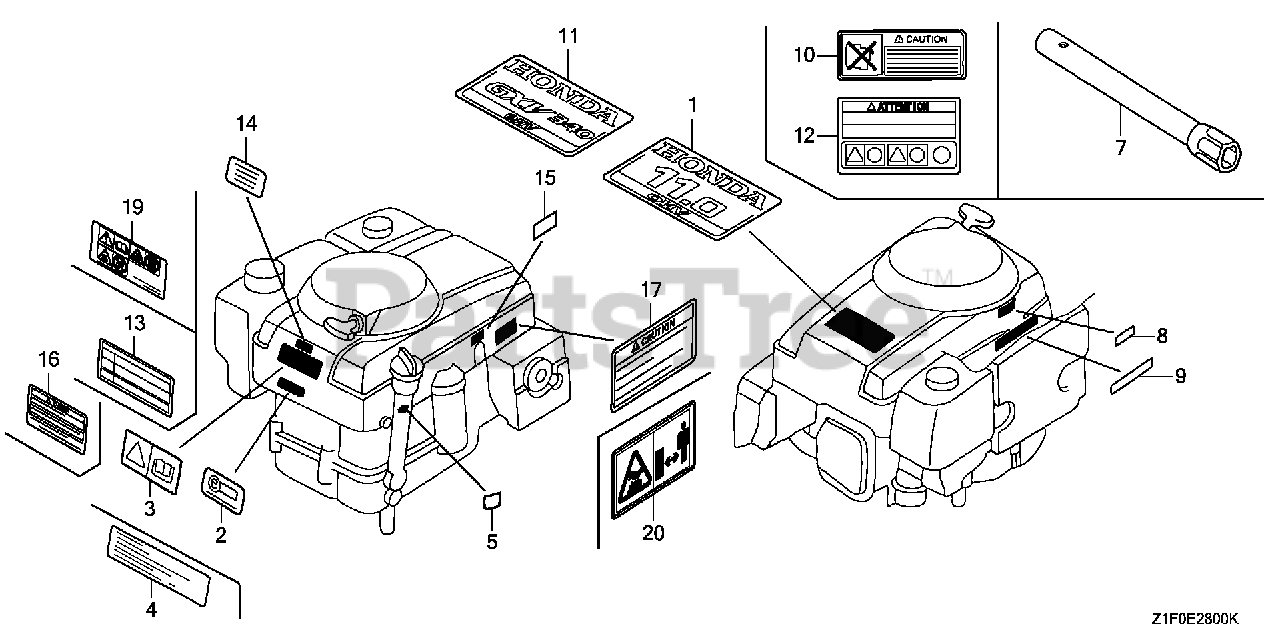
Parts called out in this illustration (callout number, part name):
1	EMBLEM, TOP COVER (11.0)
4	LABEL, CAUTION
5	MARK, TYPE (DP23)
7	WRENCH, BOX (P21)
8	LABEL, FUEL CAUTION
9	LABEL, HONDA NAME
10	LABEL, MAINTENANCE CAUTION
11	EMBLEM, TOP COVER (GXV340)
15	LABEL, WARNING (NOT CERTIFIED FOR SALE)
16	MARK, OPERATOR CAUTION
16	MARK, OPERATOR CAUTION (ENGLISH)(MADE IN THAI)
17	MARK, EX. CAUTION (ENGLISH)
